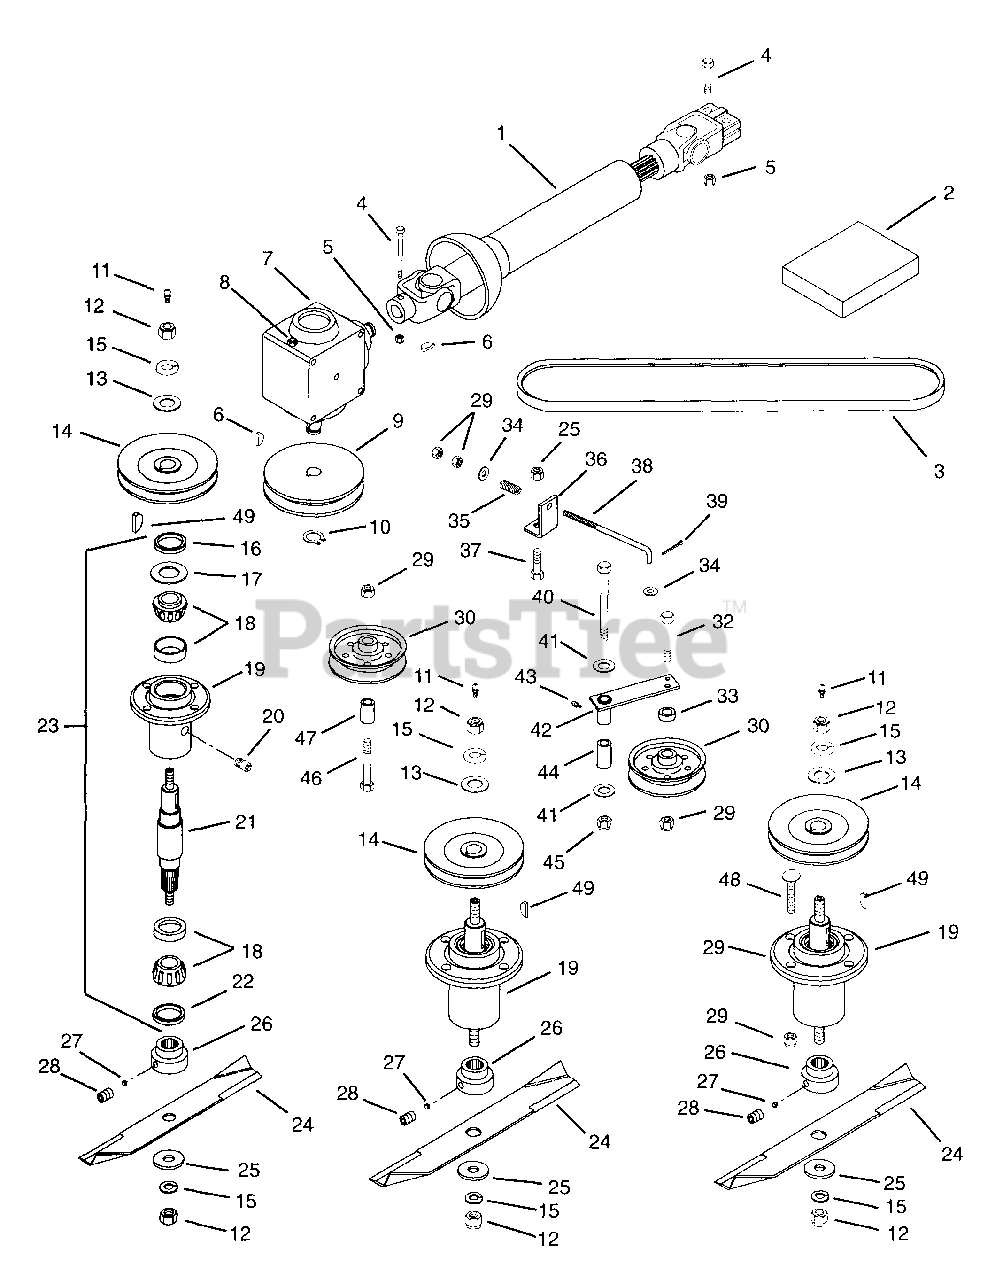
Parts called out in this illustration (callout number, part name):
1	Universal Joint Assembly
2	Kit, Repair U-Joint
3	V-Belt A-Section
4	Bolt-Hex .31-18 x 2.25 Grade 5
5	Nut-Locking-Nylon .31-18
6	Key-Woodruff .25 x .875 Hardened
7	Gear Box, Right Angle
8	Plug, 1/8 Vent
9	Sheave, Mower Gearbox
10	Ring-Retaining-External .821 x .078
11	Fitting-Lube 1/8
12	Nut-Hex .62-11
13	Washer-Flat-Steel .687 x 1.312 x .15
15	Washer-Locking .62 x .156
16	Seal 1.987 x 1.500 x .313
17	Washer-Hardened-Thrust 1.007 x 1.542 x .062
18	Assembly, Bearing Cup & Cone
19	Bearing Housing
20	Relief Fitting-Grease
21	Shaft, Spindle
22	Seal, 1.206 x 1.785 x .468
23	Service Kit Spindle Assembly
24	Blade, Mulching 50" Mower
25	Washer-Flat .640 x 1.81 x .25
28	Screw-Socket Head Cup Point Set .25-20 x .25
29	Nut-Locking-Nylon .38-16
30	Pulley-Idler 4.00 x .380
31	Bushing-Sleeve .407 x .625 x .750
32	Bolt-Hex .38-16 x 2.50 Grade 5
33	Nut-Hex .38-24
34	Washer-Flat-Steel .406 x .812 x .065
35	Spring-Compression .125 x .78 x 1.00
36	Support, Spring
37	Bolt-Hex .38-16 x 1.00 Grade 5
38	Rod, Idler
39	Pin-Cotter .09 x .75
40	Bolt-Hex .50-13 x 4.00
41	Washer-Flat-Steel .500 x 1.250 x .083
42	Weldment, Idler Pivot
43	Fitting-Lube .25-28 x .256
44	Spacer .505 x .855 x 2.50
45	Nut-Locking .50-13
46	Bolt-Hex .38-16 x 1.75 Grade 5
47	Spacer .516 x .875 x .300
48	Bolt-Round Head Square Neck .38-16 x 1.50 Grade 5
49	Key-Woodruff .25 x 1
